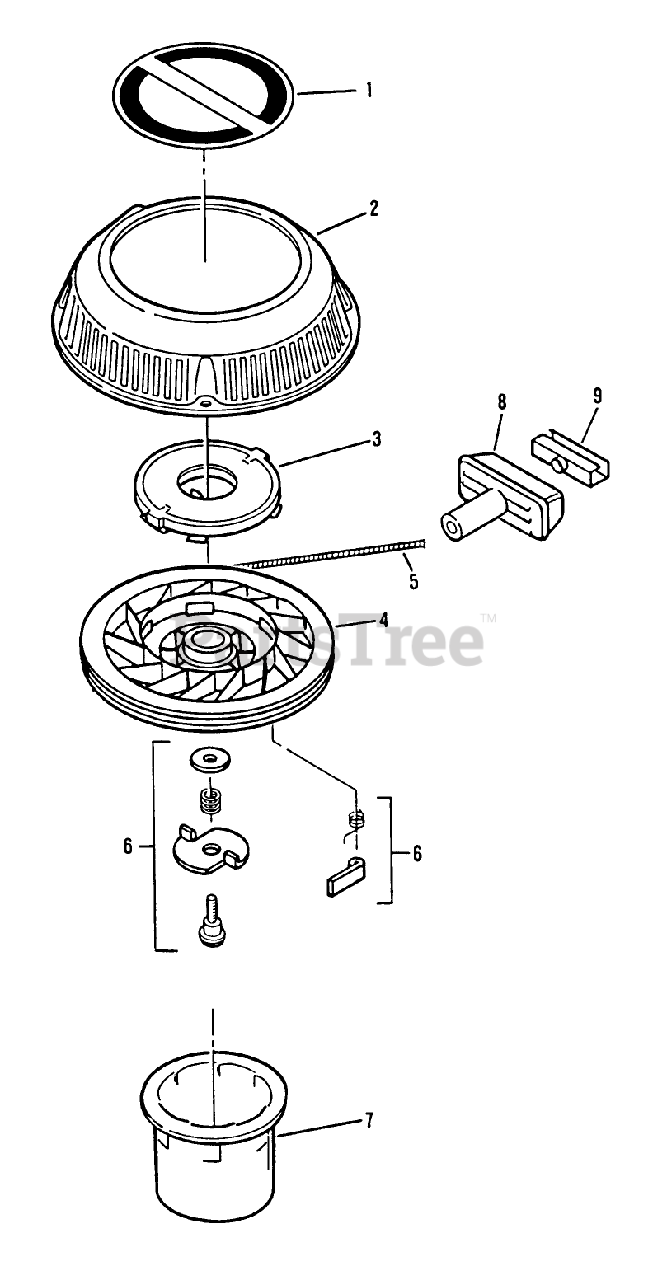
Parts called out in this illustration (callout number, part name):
4	PULLEY
6	DOG KIT
7	HUB-STARTER E COMM.
8	HANDLE START UM&D
9	CLIP-STARTER
